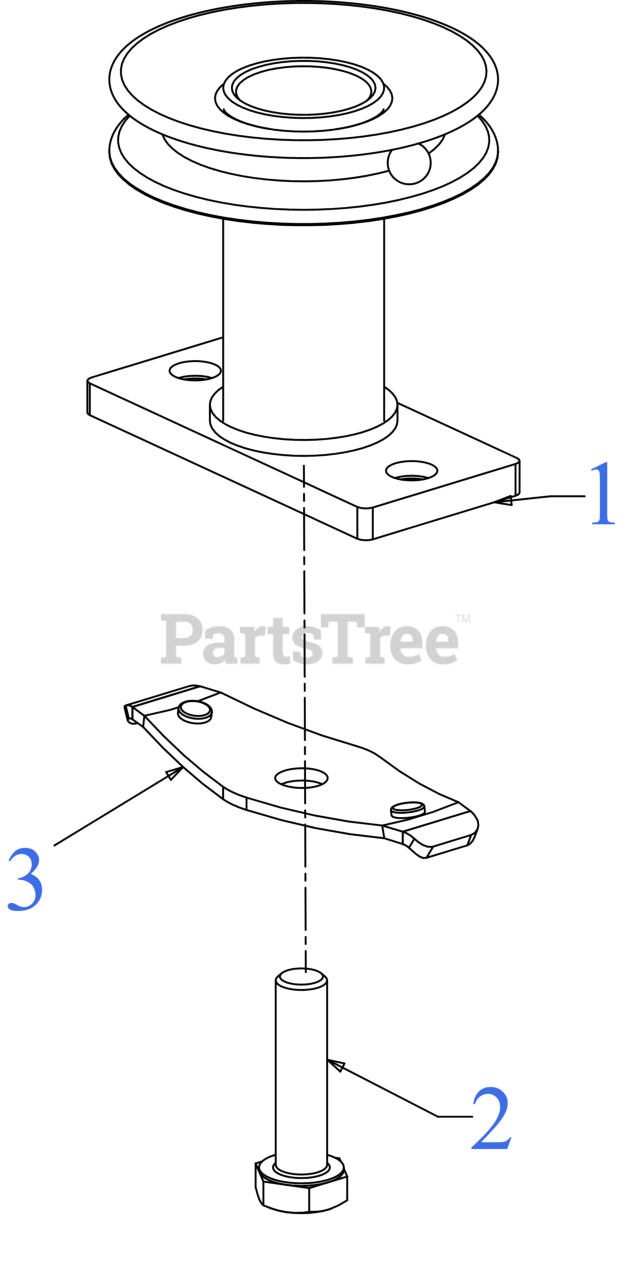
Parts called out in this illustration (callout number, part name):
1	BLADE ADAPTER
2	SCREW 3/8-24 x 1.50 GR8
3	BLADE BELL SUPPORT
